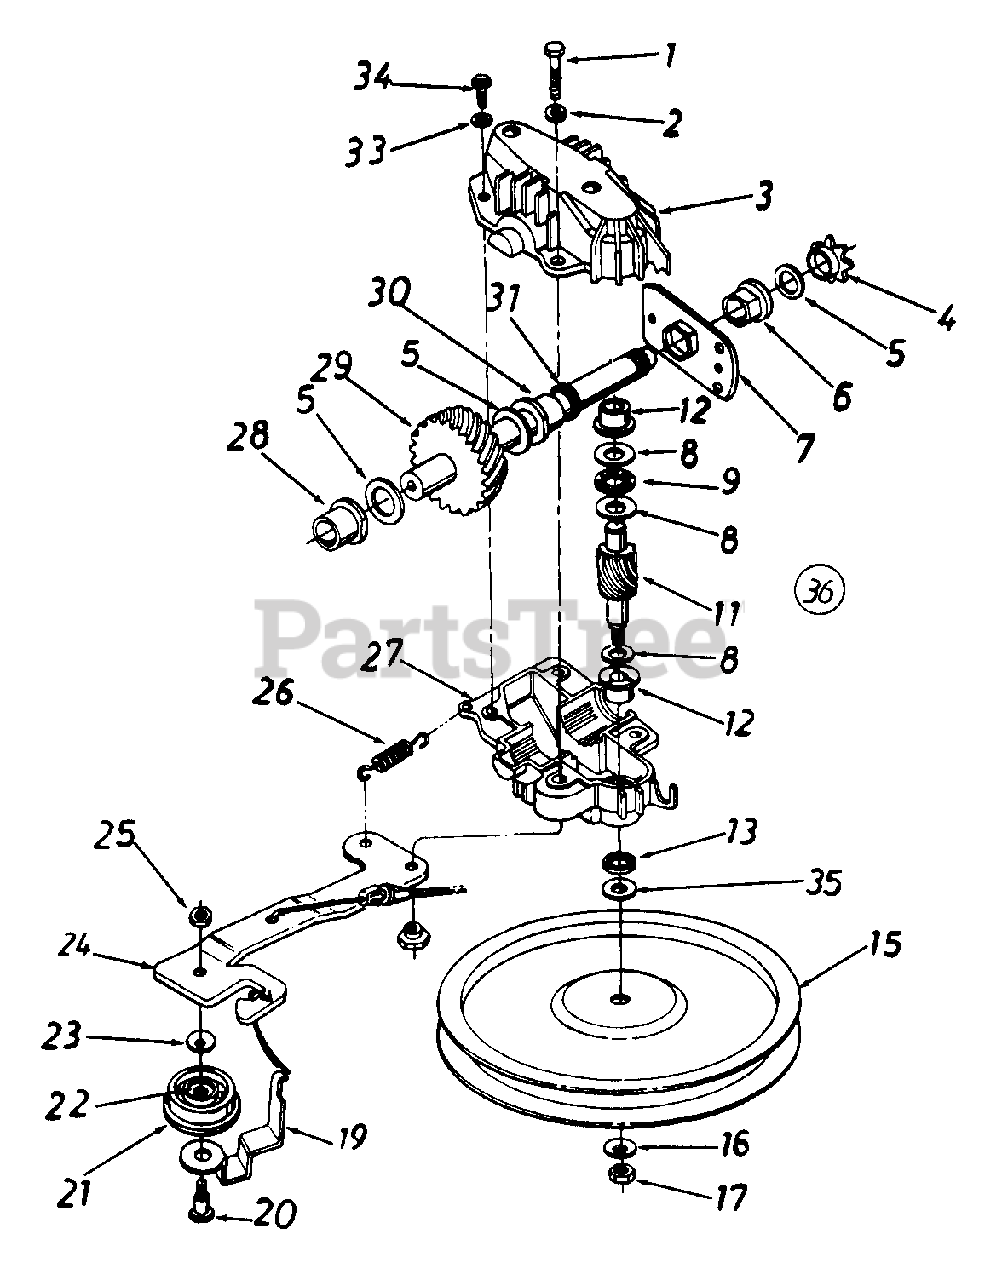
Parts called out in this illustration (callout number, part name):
1	Hex Bolt 1/4-20 x 1.25" Lg. w/Patch
2	L-Wash. 1/4" I.D.
3	Upper Hsg. Half
4	#48 Sprocket 7 Tooth x 1/2 Pitch
5	Fl-Wash. 5/8" I.D. x .030
6	Hex Flange Brg. .631" I.D.
8	Thrust Wash. .382" I.D. x .70" O.D.
9	Thrust Bearing .375" I.D. x .812" 0 D.
11	11 Tooth Pinion Shaft
12	Flange Bearing
15	Fl-Pulley 5.06" O.D.
16	Bell-Wash. .265" I.D. x .75"
17	Hex L-Nut 1/4-28 L.H. Thd.
20	Shld. Bolt .375" Dia. x .40"
21	Fl-Idler Plastic 1.50" Dia.
22	Needle Brg. .375" x .31
23	Bell-Wash. .265" I.D. x .75"
24	Idler Brk't. Ass'y.
25	Hex Patch L-Nut 1/4-28 Thd.
26	Extension Spring 1.12" Lg.
27	Lower Hsg. Half
28	Flange Bearing .566 Dia.
30	Flange Bearing .629 Dia.
31	Oil Seal .625 Dia.
33	L-Wash. #10 I.D.
34	Hex Tap Scr. #10 x .62" Lg.
35	Hex Washer .26" x .88"
36	Transmission Comp.
